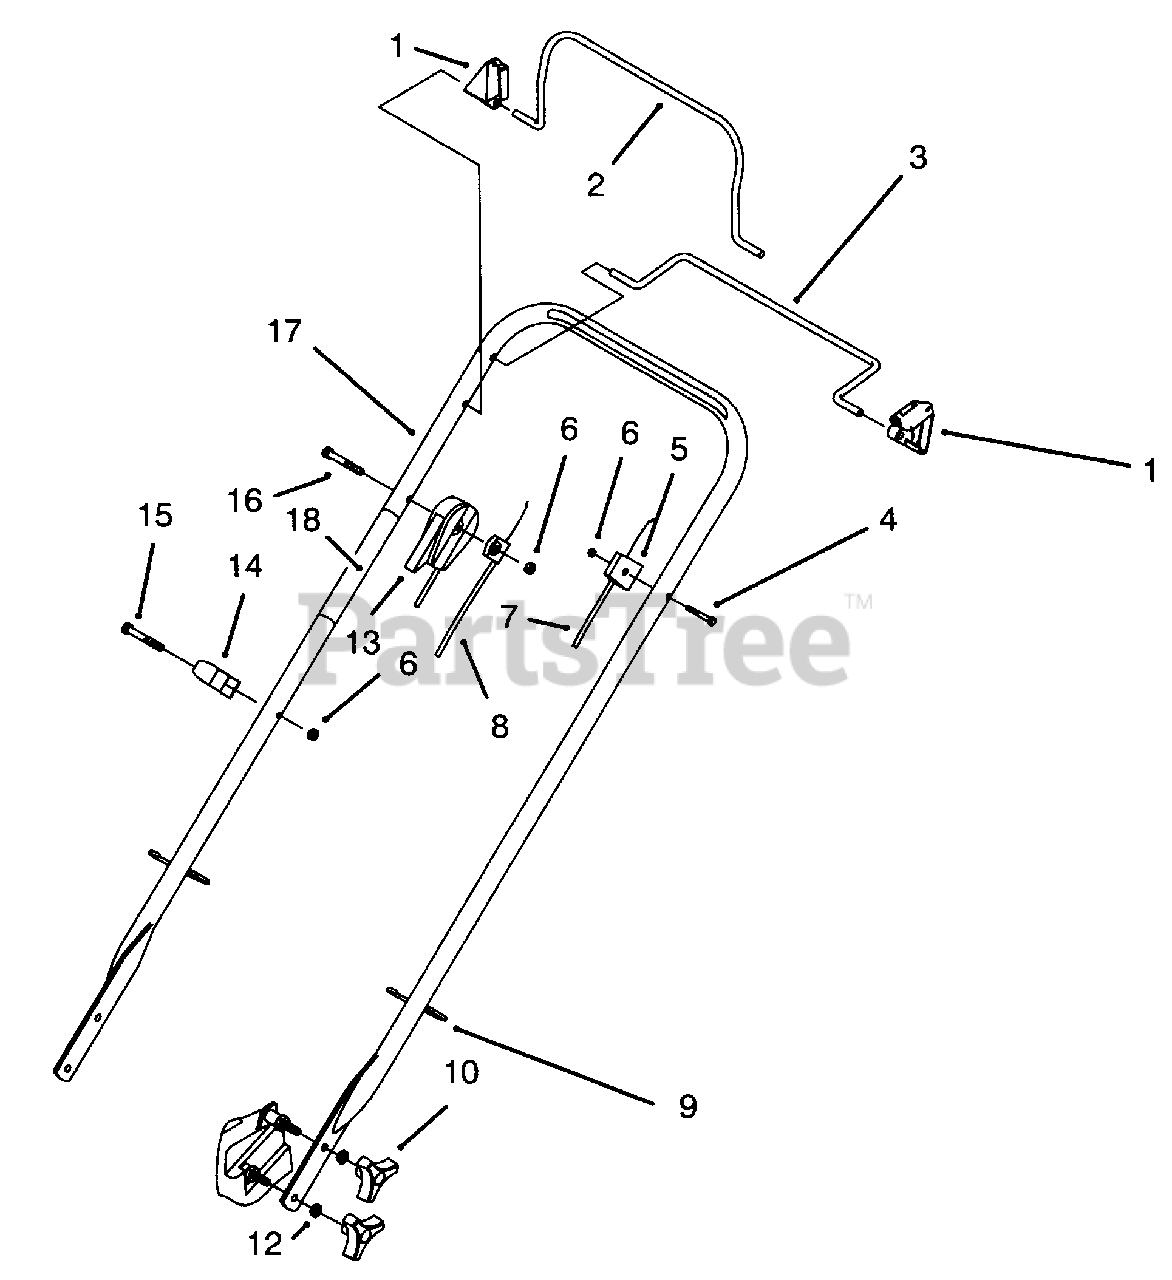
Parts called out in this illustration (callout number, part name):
1	Stop-Pivot
2	Bail-Flywheel Brake
3	Bail-S.P. Control
4	Screw-Hex Hd. Screw
5	Anchor-Cable S.P. Upper
6	Nut-Lock
7	Cable-Traction
8	Cable-Flywheel Brake
9	Tie-Cable
10	Knob
12	Washer-Lock
13	Cable-Throttle
14	Guide-Rope
15	Screw-Hex Hd. Cap
16	Screw-Hex Hd. Cap
17	Handle
18	Decal-Operation
